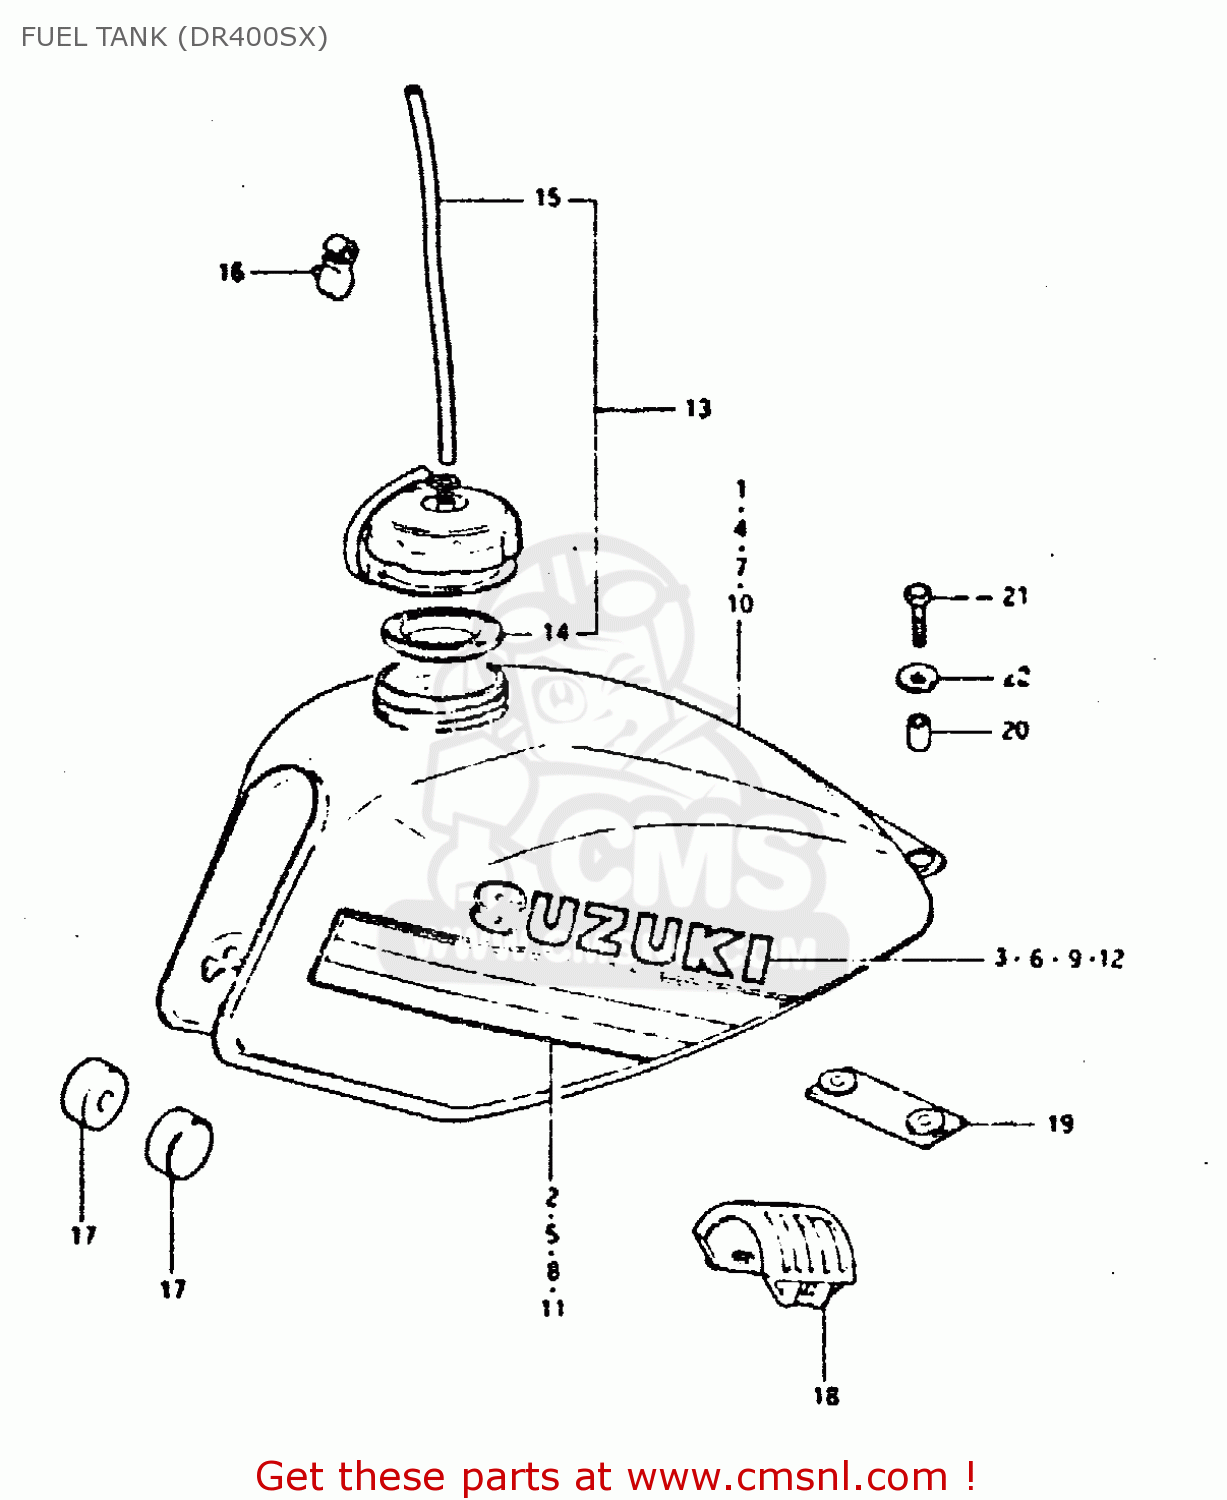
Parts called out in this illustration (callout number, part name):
1	TANK, FOOL (WHITE)
2	TAPE SET
3	EMBLEM
4	TANK, FUEL (BLUE)
5	TAPE SET
6	EMBLEM,FUEL TANK(WHITE)
7	TANK, FUEL (RED)
8	TAPE SET
9	EMBLEM,FUEL TANK(WHITE)
10	TANK, FUEL (YELLOW)
11	TAPE SET
12	EMBLEM
13	CAP SET,FUEL TANK
14	GASKET,FUEL TANK CAP (NAS)
15	HOSE
16	CLAMP,FUEL TANK BREATHER HOSE
17	CUSHION
18	CUSHION,FUEL TANK UPR FR
19	CUSHION,FUEL TANK,REAR
20	SPACER (6.1X8X15.5)
21	BOLT
22	WASHER (6.5X24X1.6)
